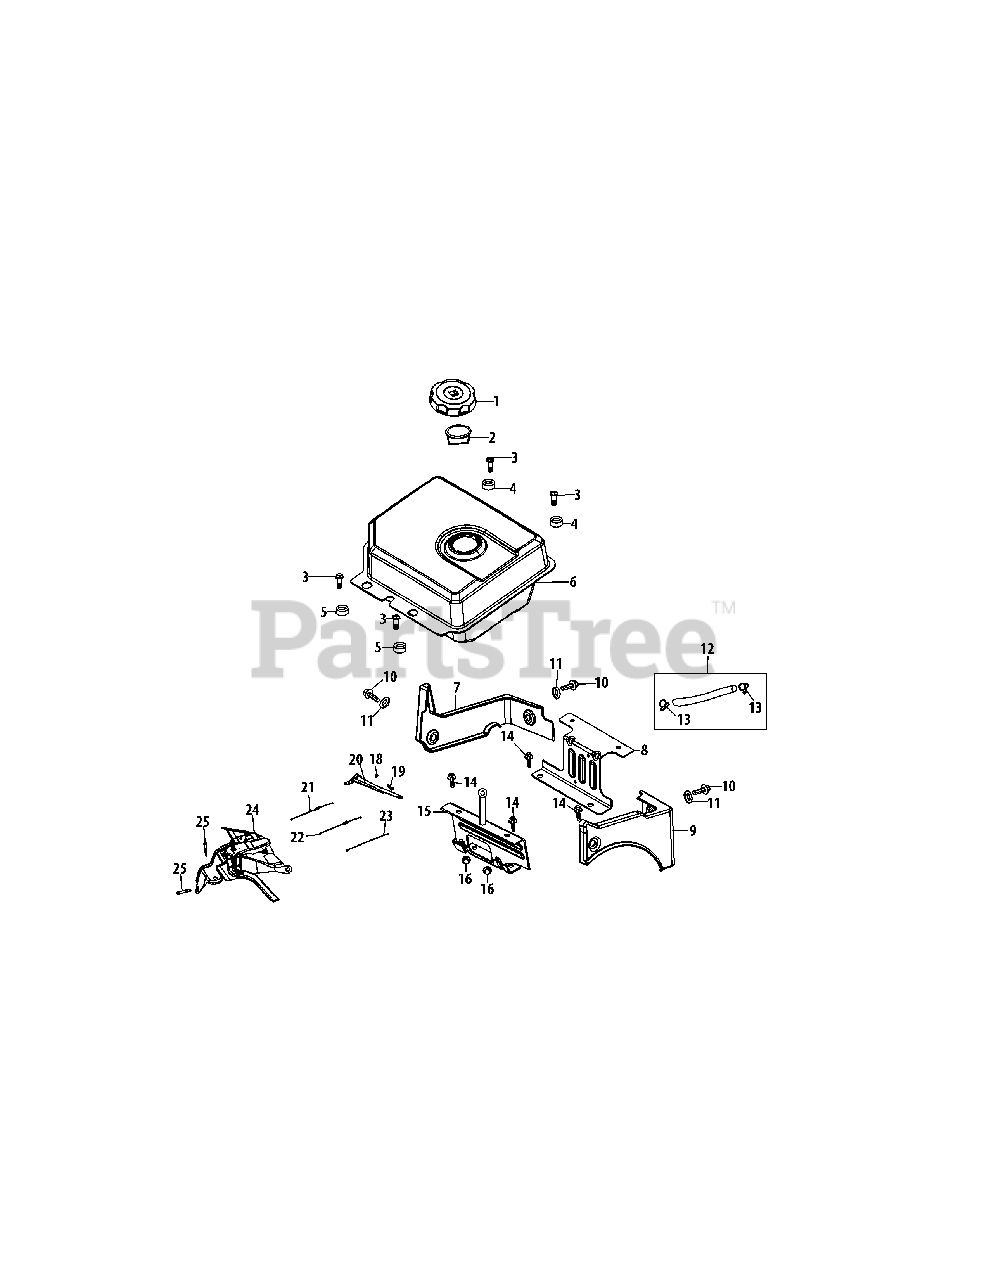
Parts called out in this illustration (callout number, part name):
1	Fuel Cap Assembly
2	Fuel Level Indocator
3	Bolt M8×20
4	Bush, Gas Tank
5	Bush, Gas Tank
6	Fuel Tank Assembly
7	Plastic Cover
8	Rear Mainting Bracket Assy.
9	Engine Cover
10	Bolt M6×16
12	Fuel Hose Fuel Hose Kit
13	Fuel Hose Clamp
14	Bolt M8×14
15	Gas Tank Bracker
18	Nut M6
19	Governor Arm Bolt
20	Governor Arm
21	Governor Spring
22	Throttle Linkage Spring
23	Governor Rod
24	Throttle Control Bracket
25	Bolt, M6×14
